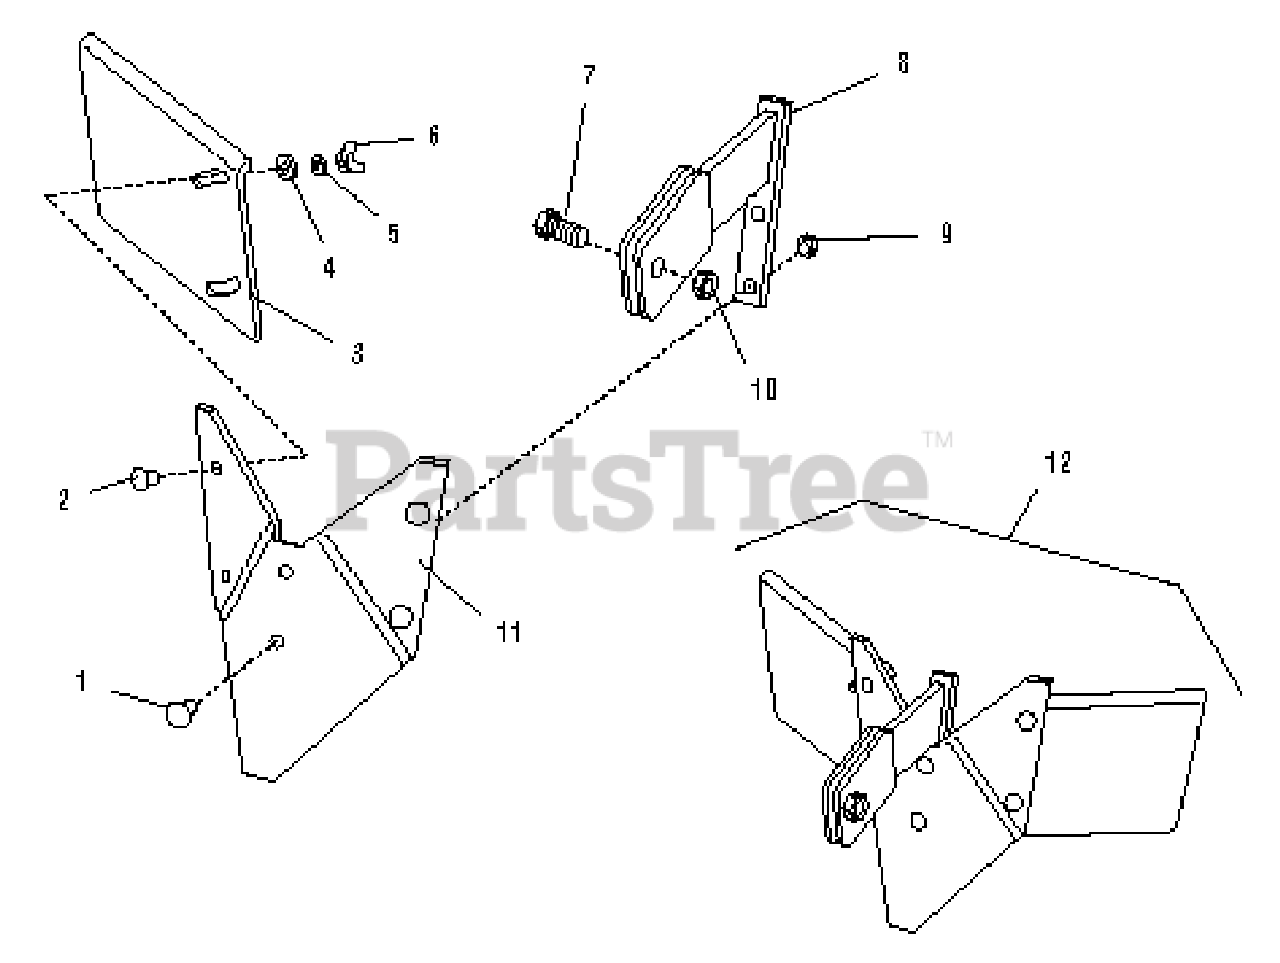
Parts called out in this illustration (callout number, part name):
1	CARRIAGE BOLT, 3/8-16 x 1-1/2
2	CARRIAGE BOLT, 5/16-18 x 3/4
3	HILLER WING, Left
4	WASHER, Flat, 5/16
5	LOCKWASHER, External Tooth, 5/16
6	WING NUT, 5/16-18
7	BOLT, Socket Head, 3/8-16 x 1-1/4
9	NUT, Nyloc, 3/8-16
10	NUT, Hex, 3/8-16
11	BLADE, Furrower
12	HILLER / FURROWER ATTACHMENT, Complete
